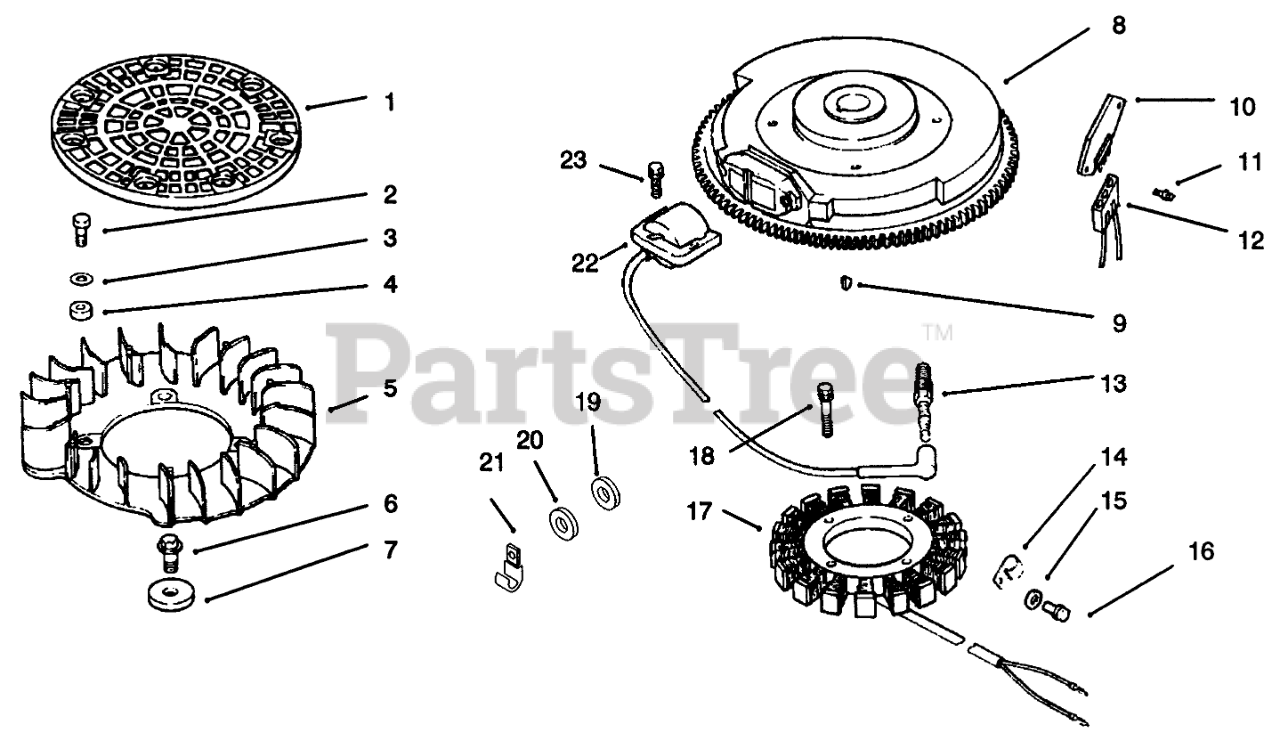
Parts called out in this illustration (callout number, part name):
1	Screen-Grass
2	Screw-Hex.
3	Washer
4	Spacer-Fan
5	Fan
6	Screw
7	Spacer-Fan
8	Flywheel ASM
9	Key
10	Rectifier-Regulator
12	Connector
13	Spark Plug
16	Screw
17	Stator-15 amp
18	Screw M5 x 0.8 x 25
19	Washer
20	Washer
21	Clip
22	Module-Ignition
23	Screw M5 x 0.8 x 20
